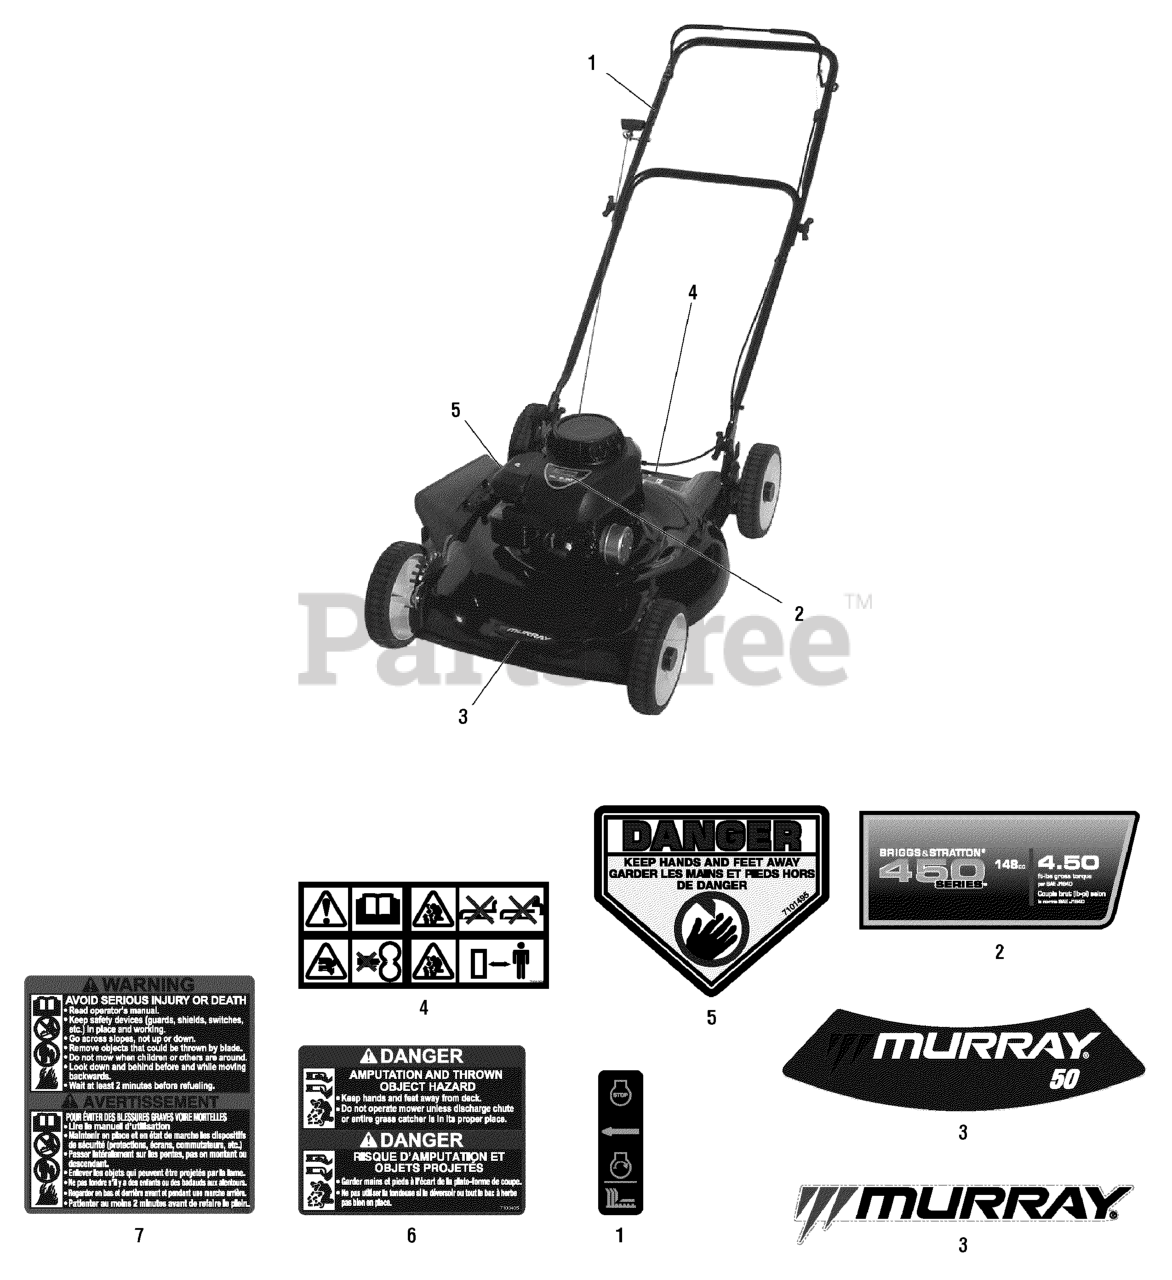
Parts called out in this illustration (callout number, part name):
1	DECAL, OPC BAIL
2	DECAL, 450 Series
3	DECAL, Murray
3	DECAL, Logo, Deck
4	DECAL, Warning, Multi Panel
5	DECAL, CPSC, FR / NG
6	DECAL, Danger, FR / ENG
7	DECAL, Warning, FR / ENG
